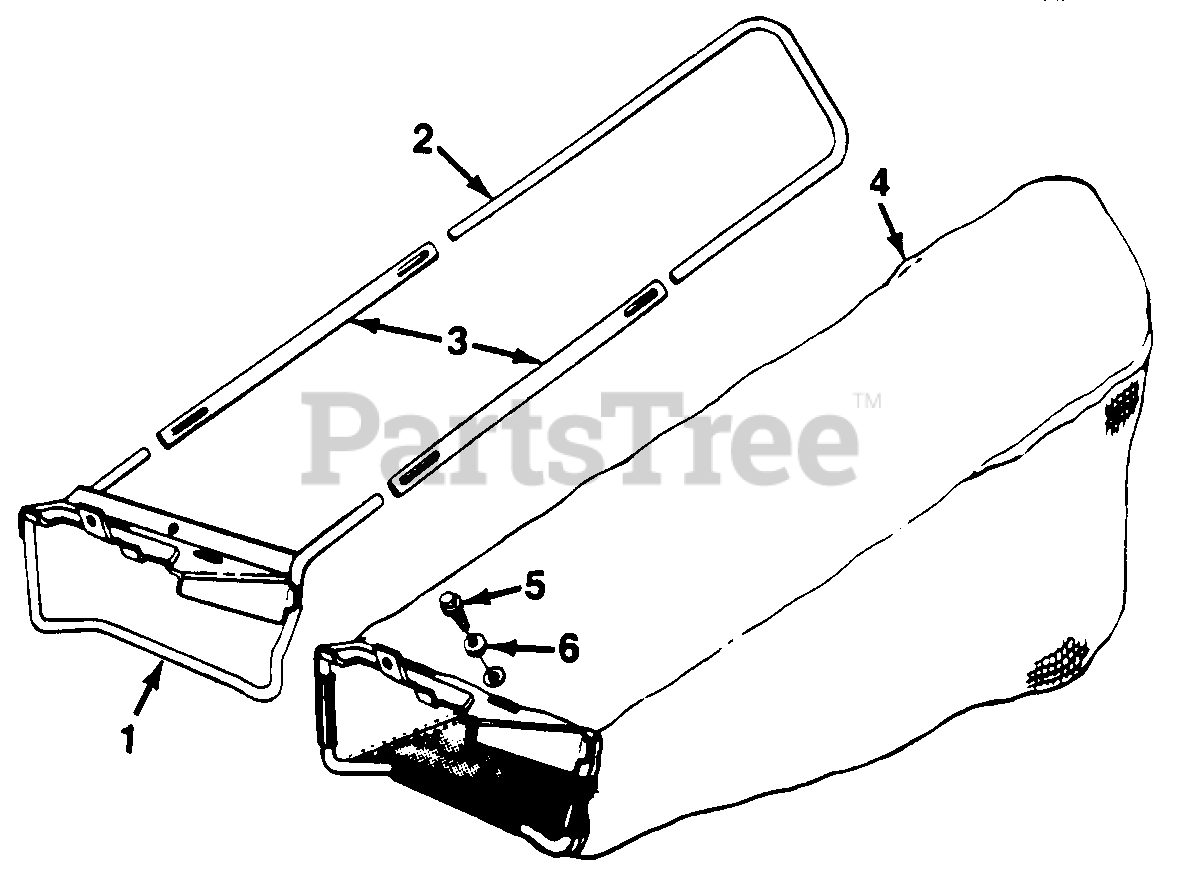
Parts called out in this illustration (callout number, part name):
4	Grass Bag
5	Hex Wash Hd. TT-Tap Scr. 1/4-20 x 5" Lg.
6	Bell-Wash. 1/4" I.D.
